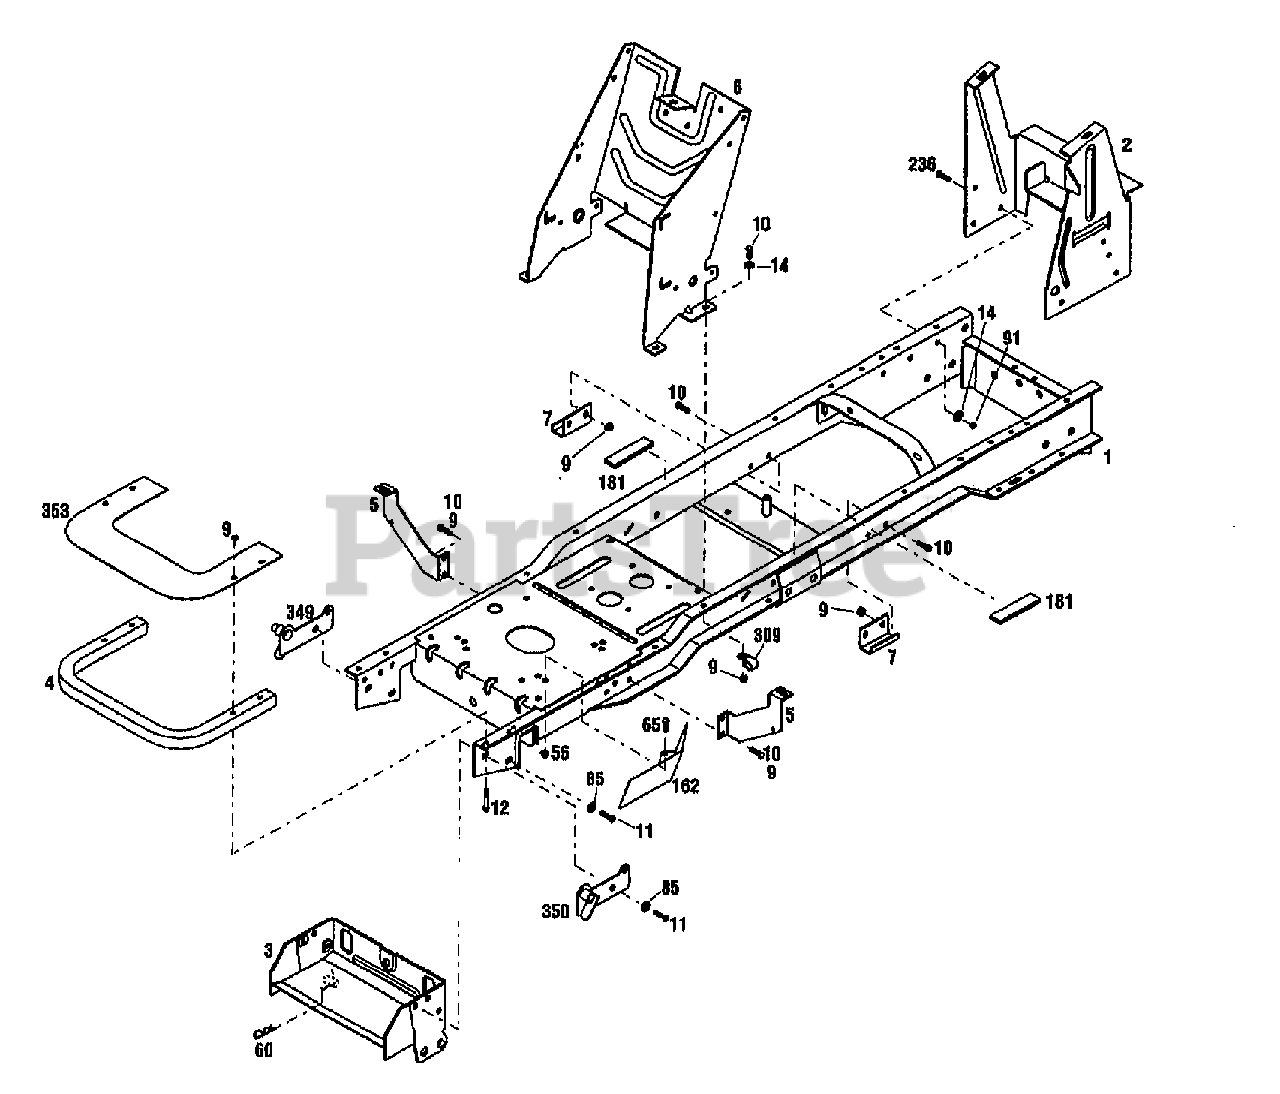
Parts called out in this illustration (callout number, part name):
2	SUPPORT-REAR TANK
3	ASSM-BRKT ATTACHMENT
4	BUMPER-FRONT
5	SUPPORT-FENDER
6	SUPPORT-CONSOLE
7	STOP-MOWER DECK
9	NUT-HFLK 5/16-18 ZP
10	SCR-HHC 5/16-18X.75 GR 5 ZP
11	SCR-HH 3/8-16X1.0 G5 ZP
12	SCR-HH 5/16-18X1.75
14	WASHER-FLAT 5/16 SAE
56	NUT-HF/LK 1/4-20 ZP
60	PIN-HITCH .125X2.56 ZP
65	SCR-HH 1/4-20X.625
85	WASHER-FLAT 3/8 SAE
91	NUT-TOP/LK 5/16-18 ZP
162	SHIELD-HEAT UPPER
236	SCR-HFLK 5/16-18X.75 ZP
309	CLIP-J
349	PLATE-PIVOT RH
350	PLATE-PIVOT LH
353	SHIELD-HEAT
